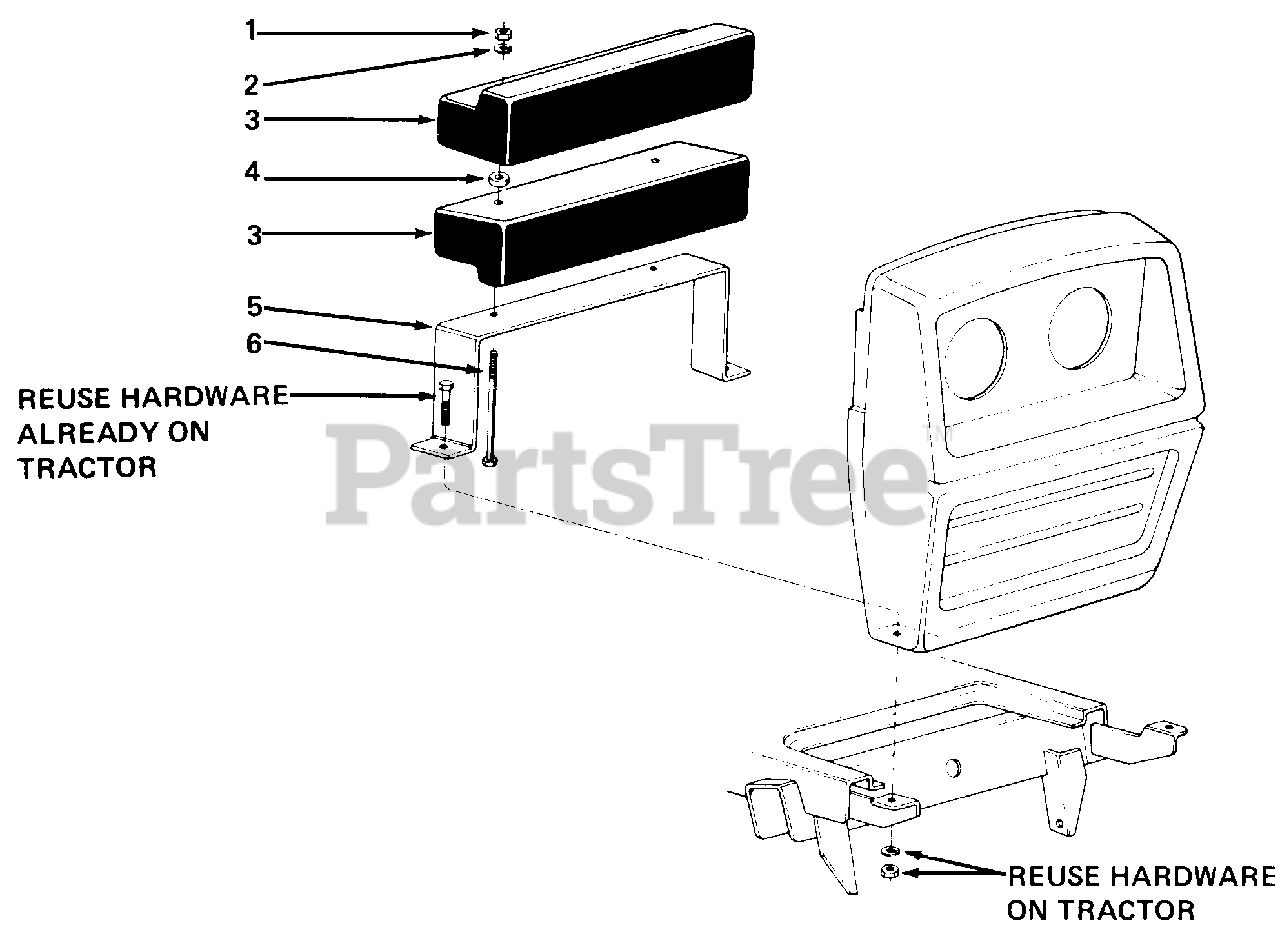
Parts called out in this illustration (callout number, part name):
1	Hex Nut 3/8-16 Thd.*
2	L.-Wash. 3/8 I.D.*
3	Weight-35 lb.
4	Spacer
5	Front Weight Bracket
6	Hex Bolt 3/8-16 x 6.5" Lg.
